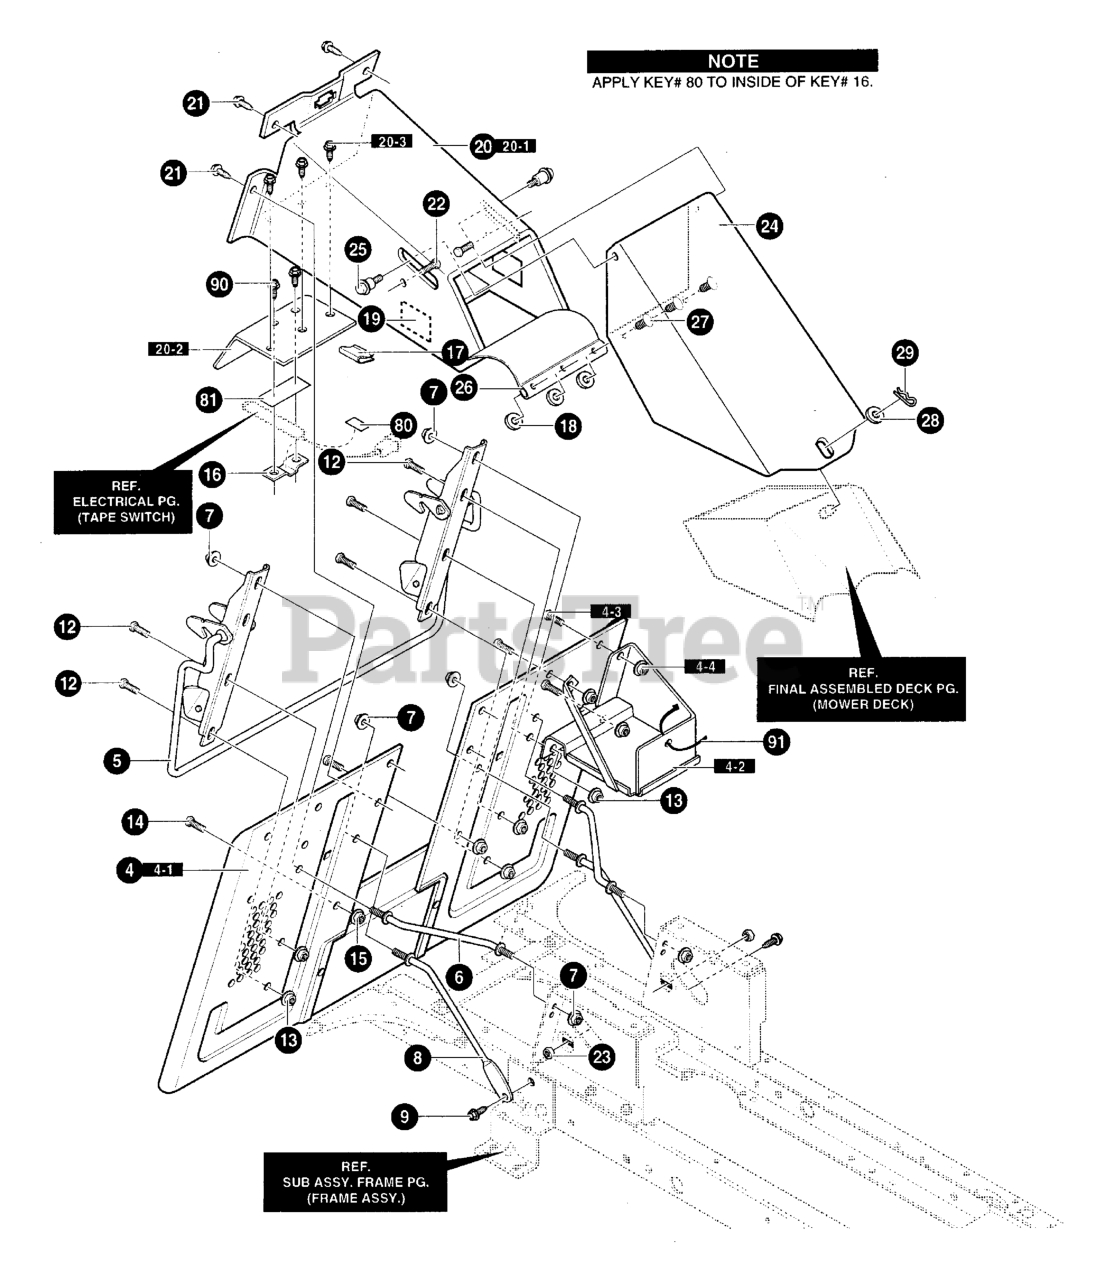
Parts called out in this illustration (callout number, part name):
4	ASSY, BACK PLATE/BATTERY
4-1	ASM. BACKPLATE FLAT
4-2	BATTERY TRAY ASM.
4-3	SCREW, 5/16-18 x 0.50 HHC
4-4	NUT, 5/16-18 HEXWDFLLK WHIZ
5	WELDMENT - LATCH LEVER
6	ROD, BRACE
7	NUT, 3/8-16 HWDFL WHIZ-LOCK
8	ROD, BRACE
9	SCREW, 5/16-18 x 0.75 HHWATAP
12	SCREW 5/16-18X.75 HXWDFL
13	NUT, 5/16-18 HEXWDFLLK WHIZ
14	SCREW 5/16-18X.75 HHWATAP
15	NUT, 5/16-18 HEXWDFLLK WHIZ
16	BRACKET, FLEX SWITCH MOUNTING
17	WIRE CLIP, ADHESIVE
18	WASHER, FLAT
19	PAD, ADHESIVE 1.00X1.50X.12
20	ASM., T/A SHIELD & UPPER CHUTE
20-1	CHUTE WELD ASM. UPPER
20-2	SHIELD, TRANSAXLE
20-3	SCREW, 1/4-20X.63 HHWATAP
21	SCREW, 5/16-18 x.75 HHC
22	BOLT, 5/16-18X.75 CARR
23	NUT, 5/16-18 HEXWDFLLK WHIZ
24	MIDDLE CHUTE ASSY
25	BOLT, .500X.453 3/8-16
26	FLAP, CHUTE
27	FASTENER, RATCHET
28	FLATWASHER .550X1.00X1 1
29	PIN, HAIR .38DIAX1.64LG
80	TAPE, DOUBLE SIDED FOAM 3/4" WD
81	TAPE, DOUBLE SIDED FOAM 3/4" WD
90	SCREW, 1/4-20X.63 HHWATAP
91	CABLE TIE
